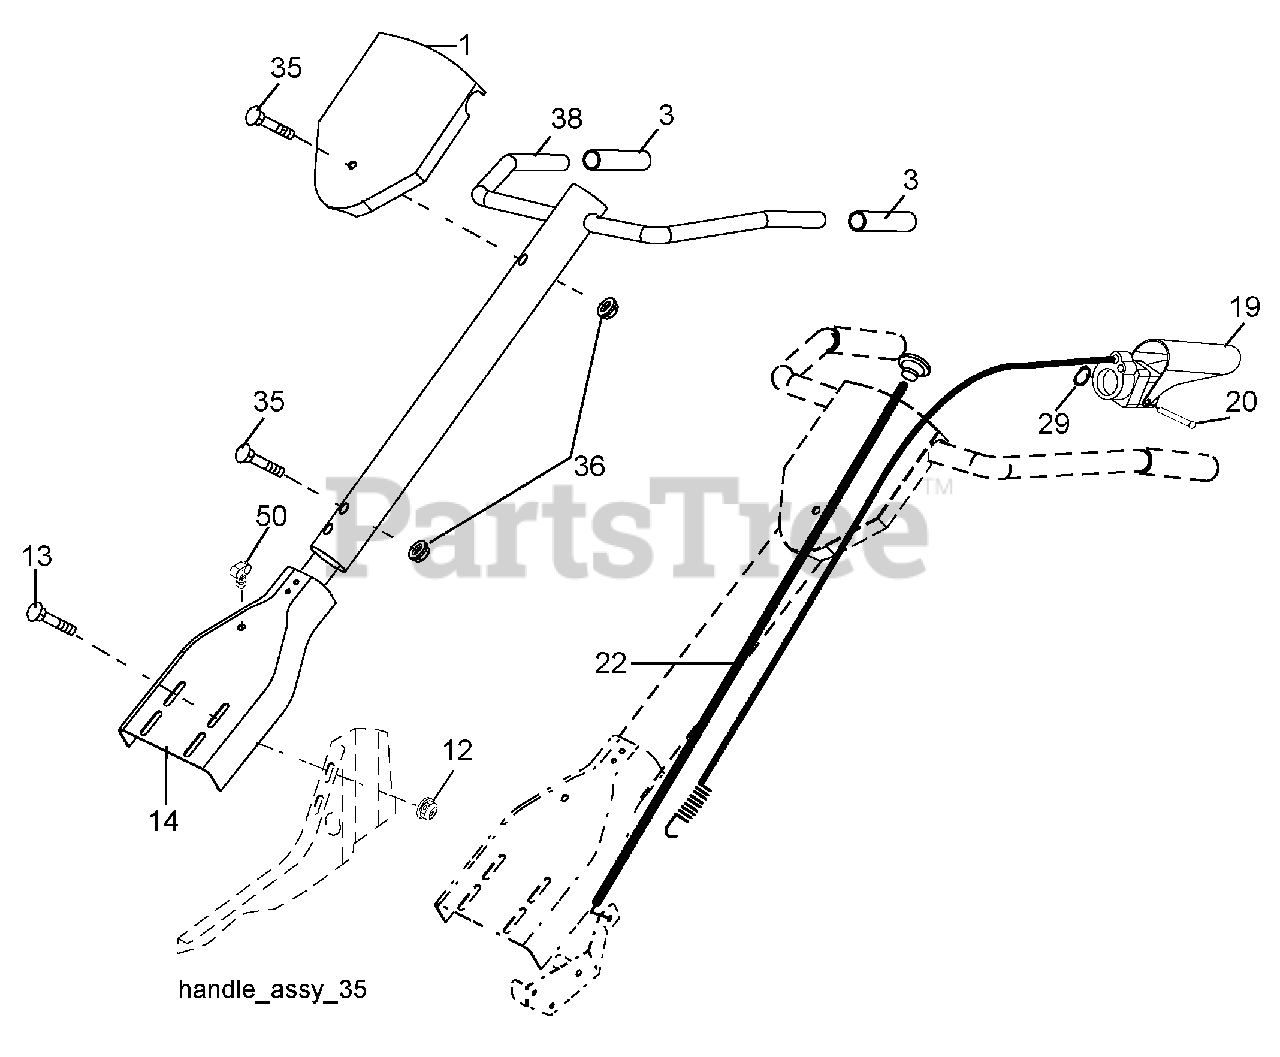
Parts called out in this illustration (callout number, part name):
1	Panel, Control
3	Grip, Handle
12	Nut, Flange
13	Bolt, Carriage 5/16-18 x 3/4
14	Assembly, Panel and Tube
19	Lever, Control, Tine
20	Pin, Pivot
22	Cable Asm Reverse
29	Retainer, Ring
35	Bolt 5/16-18 x 2-1/2
36	Locknut, Flange 5/16-18 unc
38	Assembly, Handle Column
50	Clip Routine Dual
